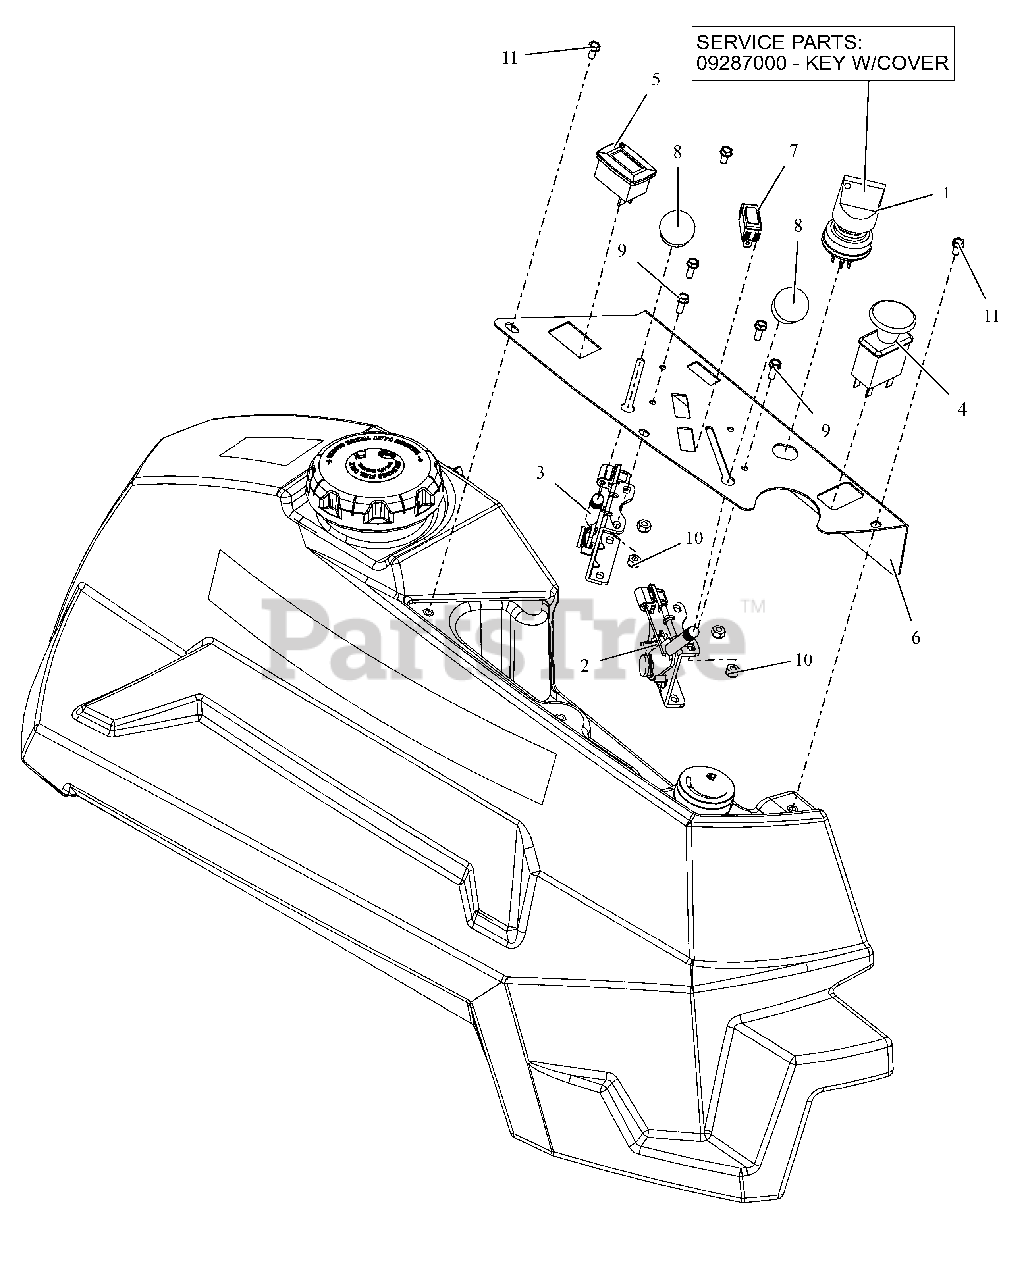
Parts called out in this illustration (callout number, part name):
1	SWITCH, IGNITION
1	KEY, W/ SHIELD
2	CABLE, PRO-CTRL 43.00"
3	CABLE, PRO-CTRL 46.00"
4	SWITCH, CLUTCH
5	METER, HOUR W/MAINTENANCE
6	PT400 CONTROL PANEL - RED
7	LIGHT, INDICATOR (RED)
8	KNOB-CONTROL-BLACK .38-16X.50
9	BLT, HWH #10-24X.50 ZCC
10	NUT-LK-NYL #10-24 G2 ZCC
11	SCR-MCH 10-24X.38 HWHSTAINLESS
